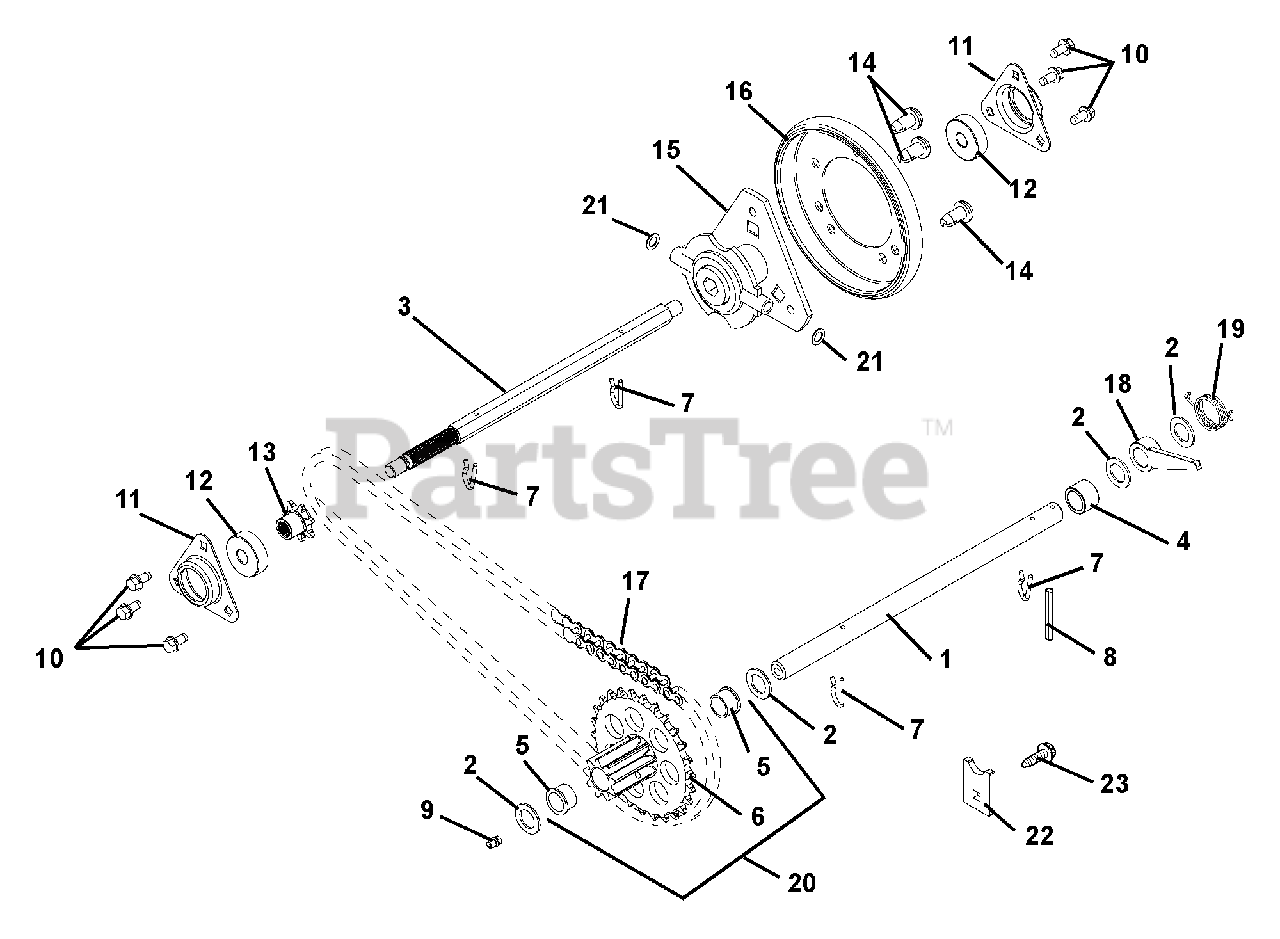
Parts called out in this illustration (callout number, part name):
1	SHAFT, PINION
2	WSHR-FL-STL .630X1.005X.062 YZ
3	SHAFT, HEX-W/SPLINE
4	SPACER, .635X.880X.611
5	BSHG-FLG .625X.750X.500X.875
6	PINION & SPROCKET
7	PIN, SPRING CLIP
8	PIN-ROLL .125X1.00
9	ZERK,FITTING .25X.125 DRIVE IN
10	@SCR-TAP .25-20X.50 HWH TR YWZ
11	FLANGE, BEARING
12	BRG-BALL .437X1.375X.437
13	SPROCKET, PINION 7T W/SPLINE
14	SCR-TAP SERRDHDTX .31-18X.50BP
15	CARRIER, DRIVE DISK
16	FRICTION, DISC
17	CHAIN - #41, 32 PITCHES
18	LEVER, LOCK ARM
19	SPRING, TORSION
20	PINION & SPROCKET W/BUSHINGS
21	WSHR-FL-STL .505X1.00X.062YWZC
22	TAB, ANTI ROTATION
23	@SCR-TAP .25-20X.50 HWH TR YWZ
